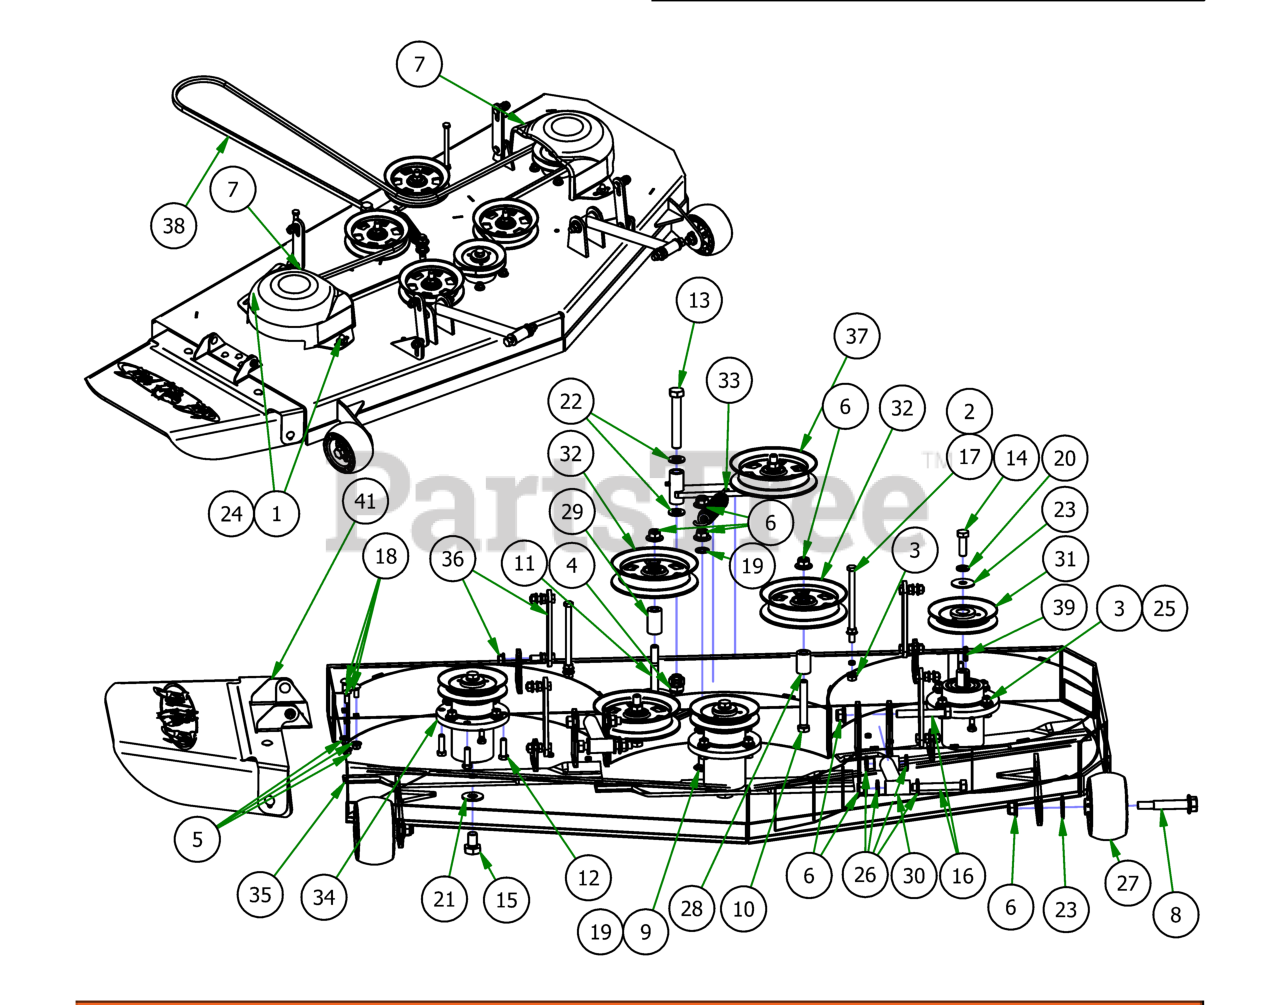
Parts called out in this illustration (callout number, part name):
1	Acorn nut-pulley Cover
2	3/8" Flange Nut
3	3/8-16 NYLON INSERT FLANGE LOCKNUT (GR.F) ZINC
4	5/8" Nylock (1/2 Jam)
5	5/16" Nylon Flange Nut
6	1/2-13 NYLON INSERT FLANGE LOCKNUT ZINC
7	Pulley Cover
8	Deck Wheel Bolt
9	1/2 x 2" Carriage Bolt
10	1/2 x 3 1/2 Flange Bolt Grade 8
11	1/2" x 4" Bolt (Grade 8)
12	3/8" x 1 1/4" Hex Bolt
13	5/8" x 4" Hex Bolt
14	1/2"-20 x 1 1/2 - Grade 5 Fine Thread Bolt
15	5/8" x 1 1/2" Grade 8 Hex Bolt (Fine)
16	1/2-13 x 3 1/2 GR 5 Hex Bolt
17	3/8-16 x 5 1/2 Hex Bolt
18	5/16-18x3/4 carriage bolt
19	.517 Square Hole Round Washer
20	1/2" Lock Washer
21	5/8'' Flat Washer
22	.630 ID Plastic Washer
23	1/2" Belleville Washer
24	.360 ID Plastic Washer-Black
25	5/16 USS FLAT WASHER (7/8 OD) ZINC
26	.505 Nylon Spacer
27	Deck Wheel
28	.502 ID X .750 OD X 1.500 Long Spacer
29	1 3/4" Pulley Spacer
30	MZ/ZT Deck Locator
31	54 MZ Spindle Pulley
32	5-3/4 Idler Pulley
33	Deck Idler Spring
34	Spindle Assembly-MZ
35	54" MZ Fusion Blade
36	Deck Hanger Assembly
37	2017 54"/48" Deck Idler Assembly
38	B155.75 Deck Belt
39	3/16 x 1 Square Key
40	2017 54" MZ Magnum Deck
41	MZ Discharge Chute Assembly
